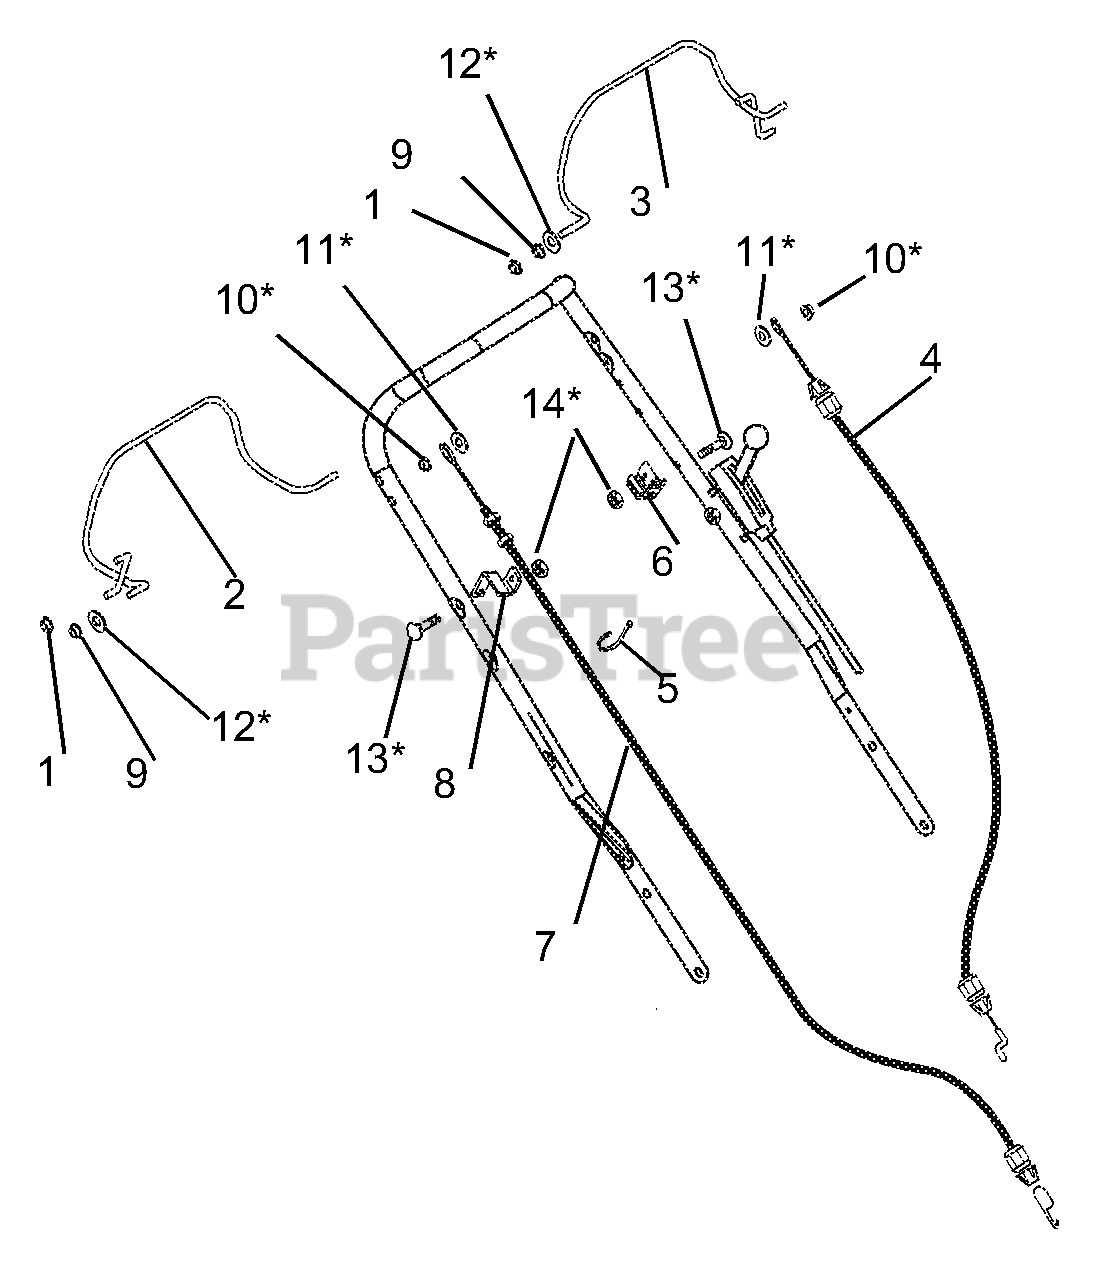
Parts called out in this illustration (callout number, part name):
1	NUT-PUSH .312 DIA. PAL
2	BAIL, TRACTION (WLDMENT)
3	BAIL, ENGINE WELDMENT
4	CABLE, ENGINE (BRIGGS/GXV)
4	CABLE, WBLM ENGINE
4	CABLE, HONDA GCV ENGINE
5	CABLE TIE LG 5-1/2
6	ANCHOR, WBLM ENGINE CABLE
7	CABLE, WBLM TRACTION
8	ANCHOR, CABLE
9	BSHG-FLG .325X.444X.440X.560
10	1/4" Push Nut
11	9/32" Washer
12	1/4" Washer
13	1/2" x 1/4" Bolt
14	1/2" Locknut
